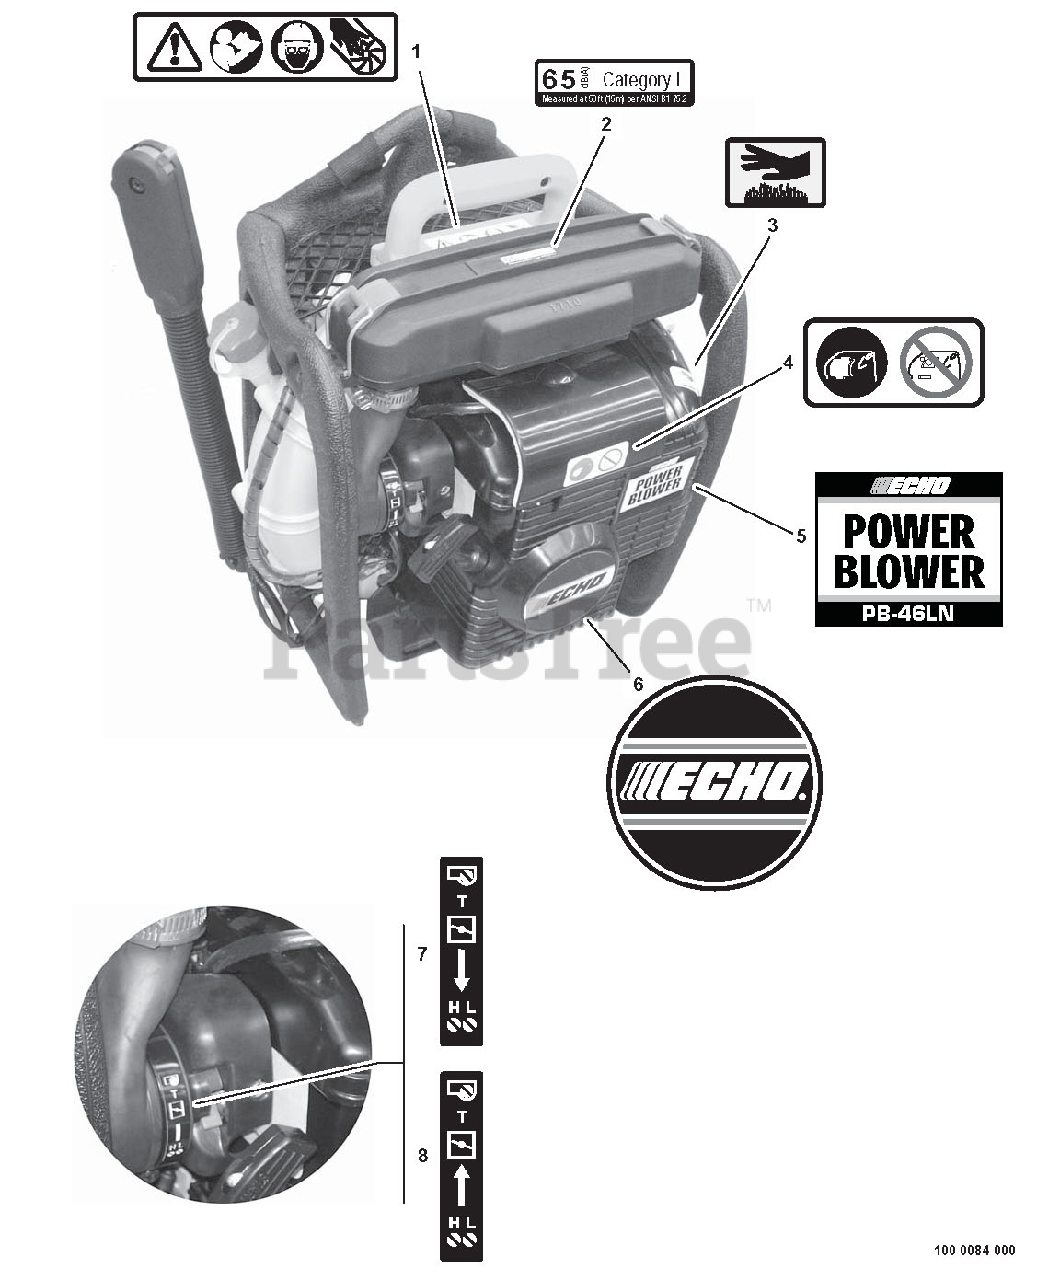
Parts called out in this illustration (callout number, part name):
1	LABEL - CAUTION
2	LABEL - NOISE 65dB(A) CAT I
3	LABEL - HOT SURFACE
4	LABEL - HOT SURFACE
5	LABEL - MODEL PB-46LN
6	LABEL - ECHO
7	LABEL - CHOKE
8	LABEL - CHOKE
